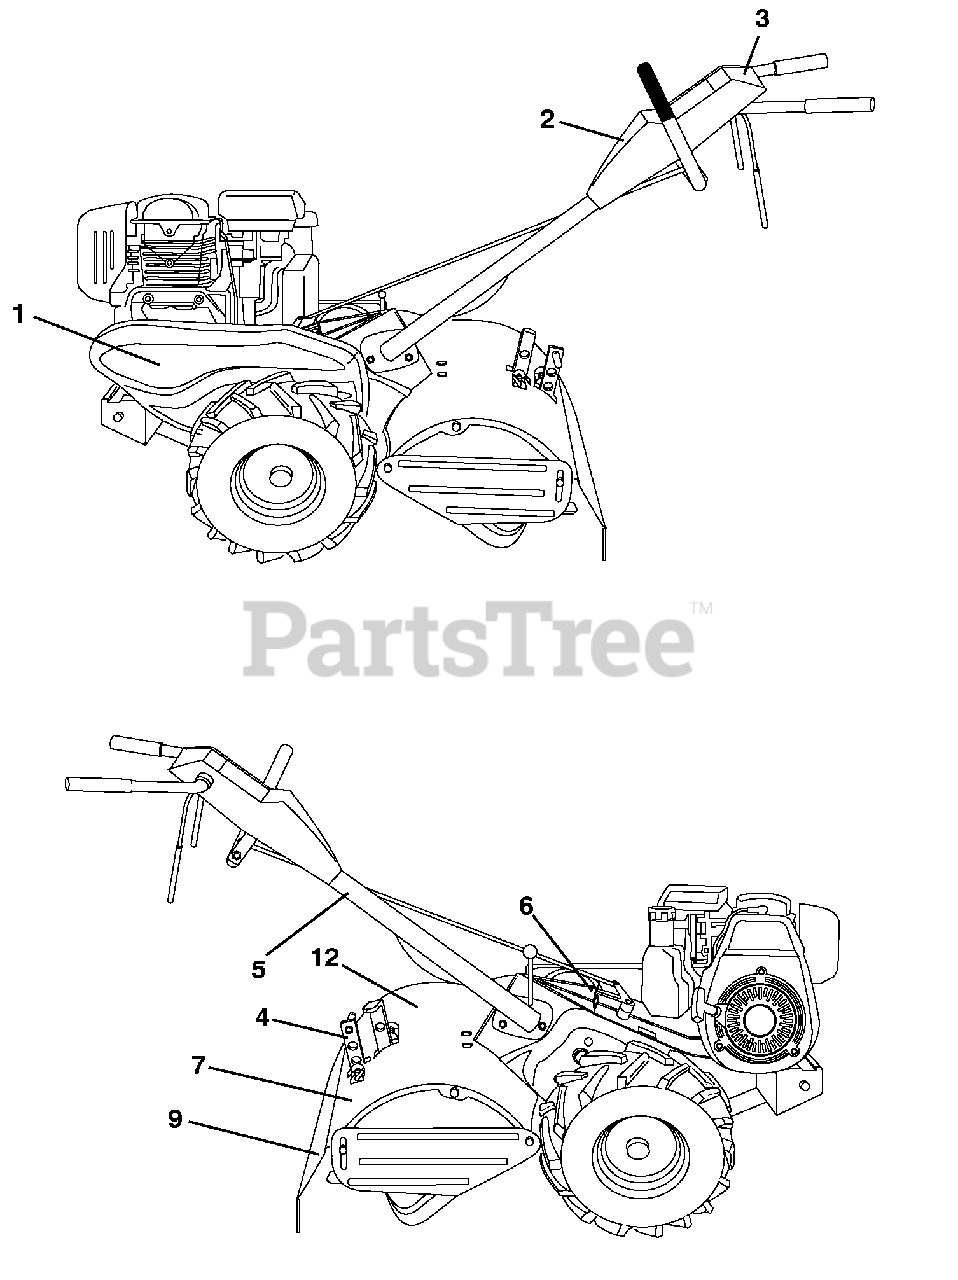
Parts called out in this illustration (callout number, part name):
1	Decal, Belt Guard
2	Decal, Console
3	Decal, Console
4	Decal, Tine Shield
5	Decal, Hand Placement
6	Decal, Shift Indicator
7	Decal, Reverse
9	Decal, Warning, Rotating Tines
12	Decal, Forward
